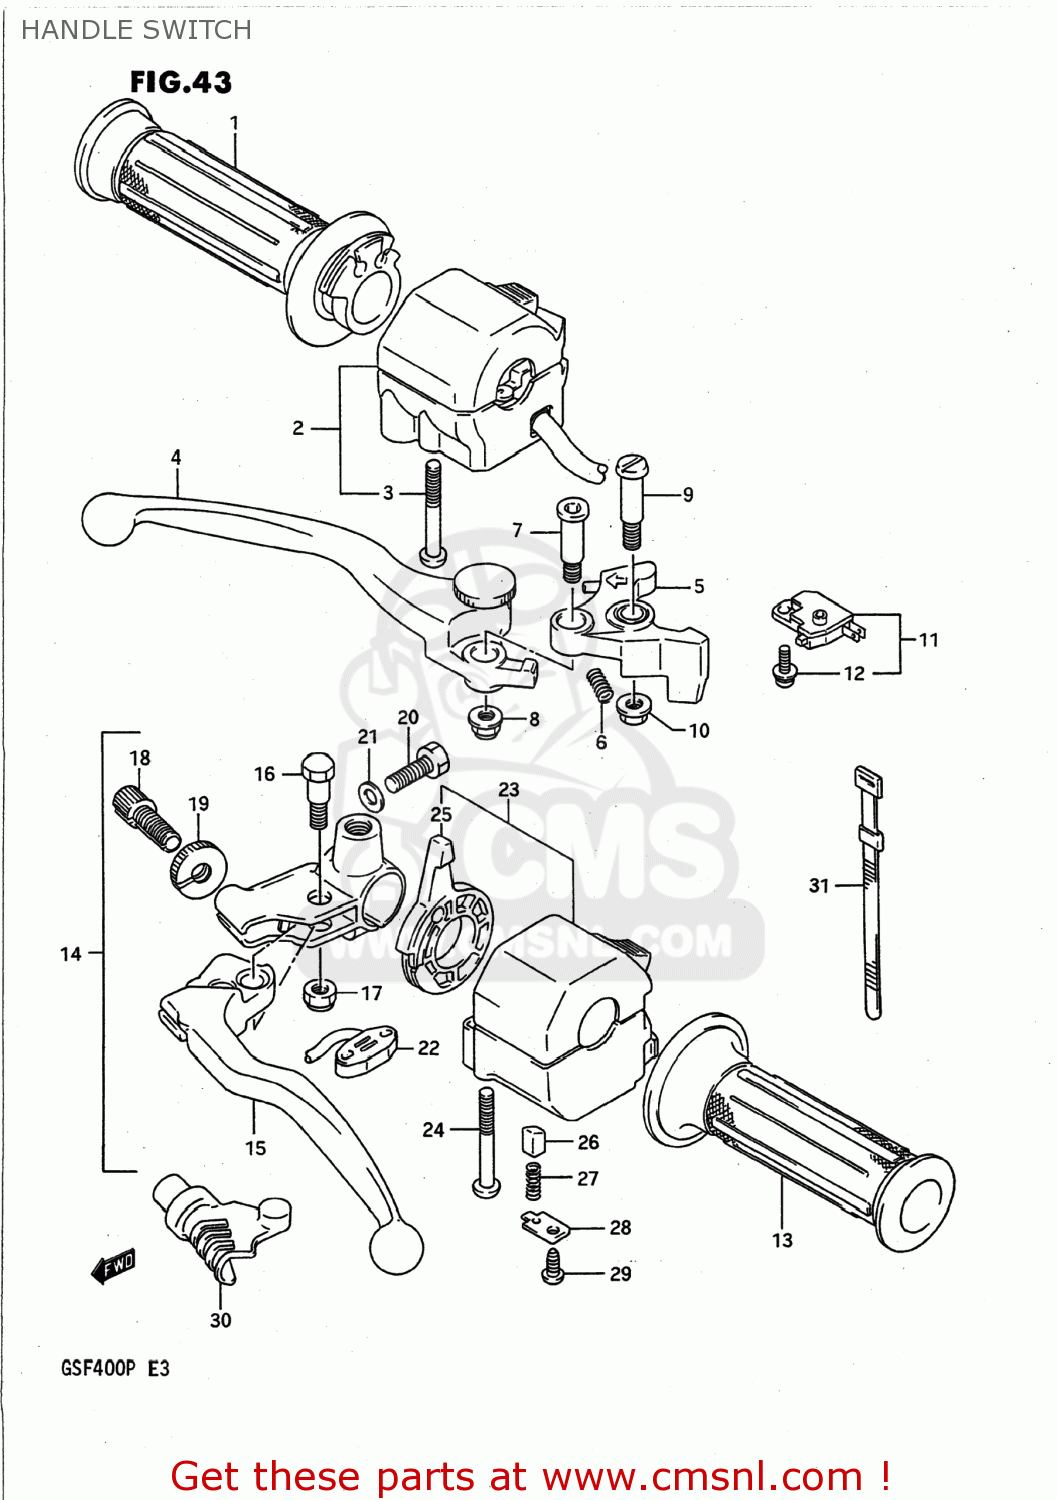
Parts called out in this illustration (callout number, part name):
1	GRIP,THROTTLE
2	SWITCH ASSEMBLY,HANDLE,RIGHT
3	SCREW, 5X45
4	LEVER,ADJUST
5	KNOCKER
6	SPRING
7	BOLT,LEVER
8	NUT
9	BOLT,LEVER PIVOT
10	NUT 6MM
11	SWITCH ASSEMBLY,STOP
12	SCREW
13	GRIP,L
14	LEVER ASSEMBLY,CLUTCH
15	LEVER,CLUTCH
16	BOLT,LEVER
17	NUT
18	ADJUSTER,CABLE
19	NUT,CABLE ADJUSTER
20	BOLT
21	WASHER
22	SWITCH ASSEMBLY,CLUTCH
23	SWITCH ASSEMBLY,HANDLE,LEFT
24	SCREW, 5X45
25	LEVER,CHOKE
26	PIECE,SLIDE
27	SPRING
28	PLATE
29	SCREW
30	COVER,CLUTCH LEVER
31	CLAMP(L:120)
